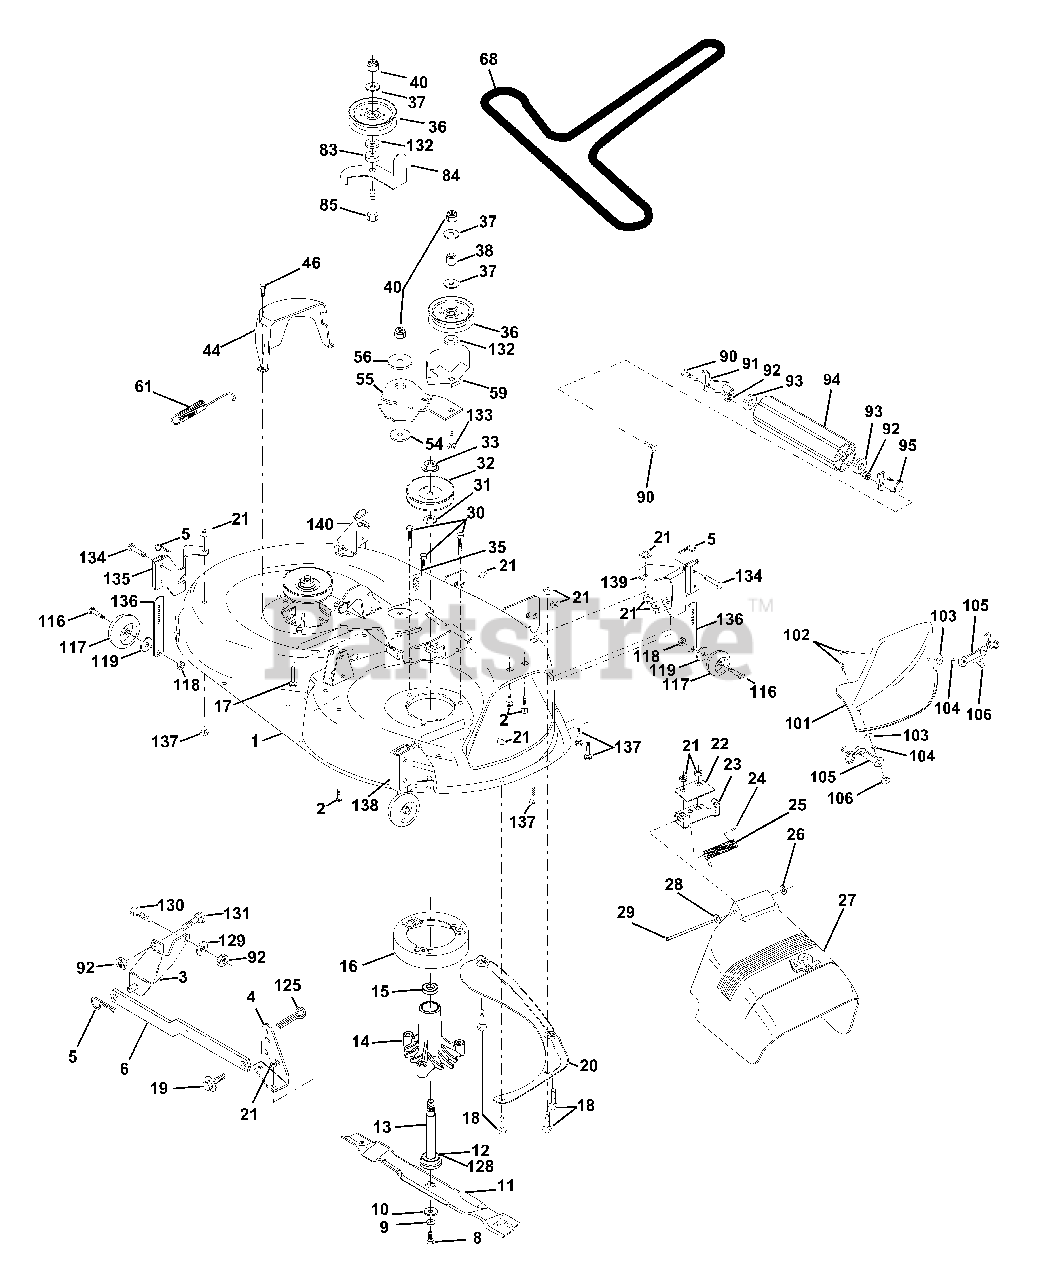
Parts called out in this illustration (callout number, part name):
1	Housing Asm Mower 42"w/aadj
2	Bolt Rdhd Sqnk 5/16-18unc X3/4
3	Bracket Asm Fr Sway Bar 38/42
4	Bracket Asm Deck 42"sway Bar
5	Retainer Spring
6	Arm Suspension Rear
8	Bolt 3/8-24x1 25 Gr8 Patched
9	Washer Lock Hvy 3/8 Unplated
10	Washer Hard Blade Mower Vented
11	Blade Mower Mulching 42"
12	Bearing Ball #6204 (Mandrel)
13	Shaft Asm W/lower Bearing
14	Housing Mandrel Vented(machd)
15	Bearing Ball Mandrel
16	Stripper Round Mower
17	Bolt Rdhd Sqnk 3/8-16 X 2-1/4
18	Bolt Carr 5/16-18 X 5/8
19	Bolt Shoulder
20	Baffle Vortex 42
21	Nut Crown Lock 5/16-18
22	Stiffener Bracket 42"deck
23	Bracket Deflector Mower 42"
24	Cap Sleeve 80x 112 Blk Mower
25	Spring Torsion Deflector 2 52
26	Nut Push Phos & Oil
27	Shield Deflector Mower 42" Blk
28	Washer 11/32 X 5/8 X 16 Ga
29	Rod Hinge 42"6 75 Wlg
30	Screw Thdrol Washer Head
31	Washer Spacer Mower Vented
32	Pulley Mandrel 42"
33	Nut 9/16top Lock Flng Cntr
35	Fastner Christmas Tree
36	Pulley Idler Flat 3 060
37	Washer 13/32 X 13/16 X 16 Ga
38	Spacer Spring Stop Idler
40	Nut Lock 3/8-16 Unc
44	Guard Mandrel LH Black
46	Screw Thdrol 1/4-20x5/8
54	Washer Hardened
55	Arm Idler 42"mower LT/YT
56	Spacer Retainer Pm Mower
59	Guard, Belt
61	Spring Ext. Elect
68	V-Belt Mower
83	Washer Sintered
84	Keeper 'Belt Idler
85	Bolt Carriage 3/8-16 x 2-1/4 Gr.5
90	Bolt Fin Hex 3/8-16unc X 1
91	Bracket Asm Noseroller LH
92	Nut Lock Hex w/ins. 3/8-16 UNC
93	Washer 17/32 X 7/8 X 16 Ga
94	Roller Nose 38 & 42
95	Bracket Asm Noseroller RH
101	Cover Mulching 42" Blk
102	Screw
103	Washer #10
104	Washer Lock #10
105	Latch Asm Bagger
106	Nut Weld .327/.304 #10-24
116	Bolt Shld
117	Wheel Gauge Donut
118	Nut Centerlock 3/8 - 16 UNC
119	Washer 3/8 x 7/8 x 14 Ga.
125	Cotter Pin
128	Washer Felt
129	Washer 13/32 x 13/16 x 12 Ga.
130	Bolt Fin Hex 3/8-16unc x 1 Gr. 5
131	Bolt Rdhd Sqnk 3/8-16 UNC
132	Washer 13/32 x 1-3/8 x 3 Ga.
133	Bolt RDHD 3/8-16 Unc x 2-3/4 Gr.5
134	Pin Head Rivet
135	Bracket Asm Whl Ga Rear Lh 42"
136	Bar Adjusting Gauge Wheel
137	Bolt Caarr. 5/16-18 x 5/8 Short
138	Bracket Asm Whl Ga Rear Rh 42
139	Bracket Asm Whl Ga Front Rh 42
140	Bracket Asm Whl Ga Front Lh 42
